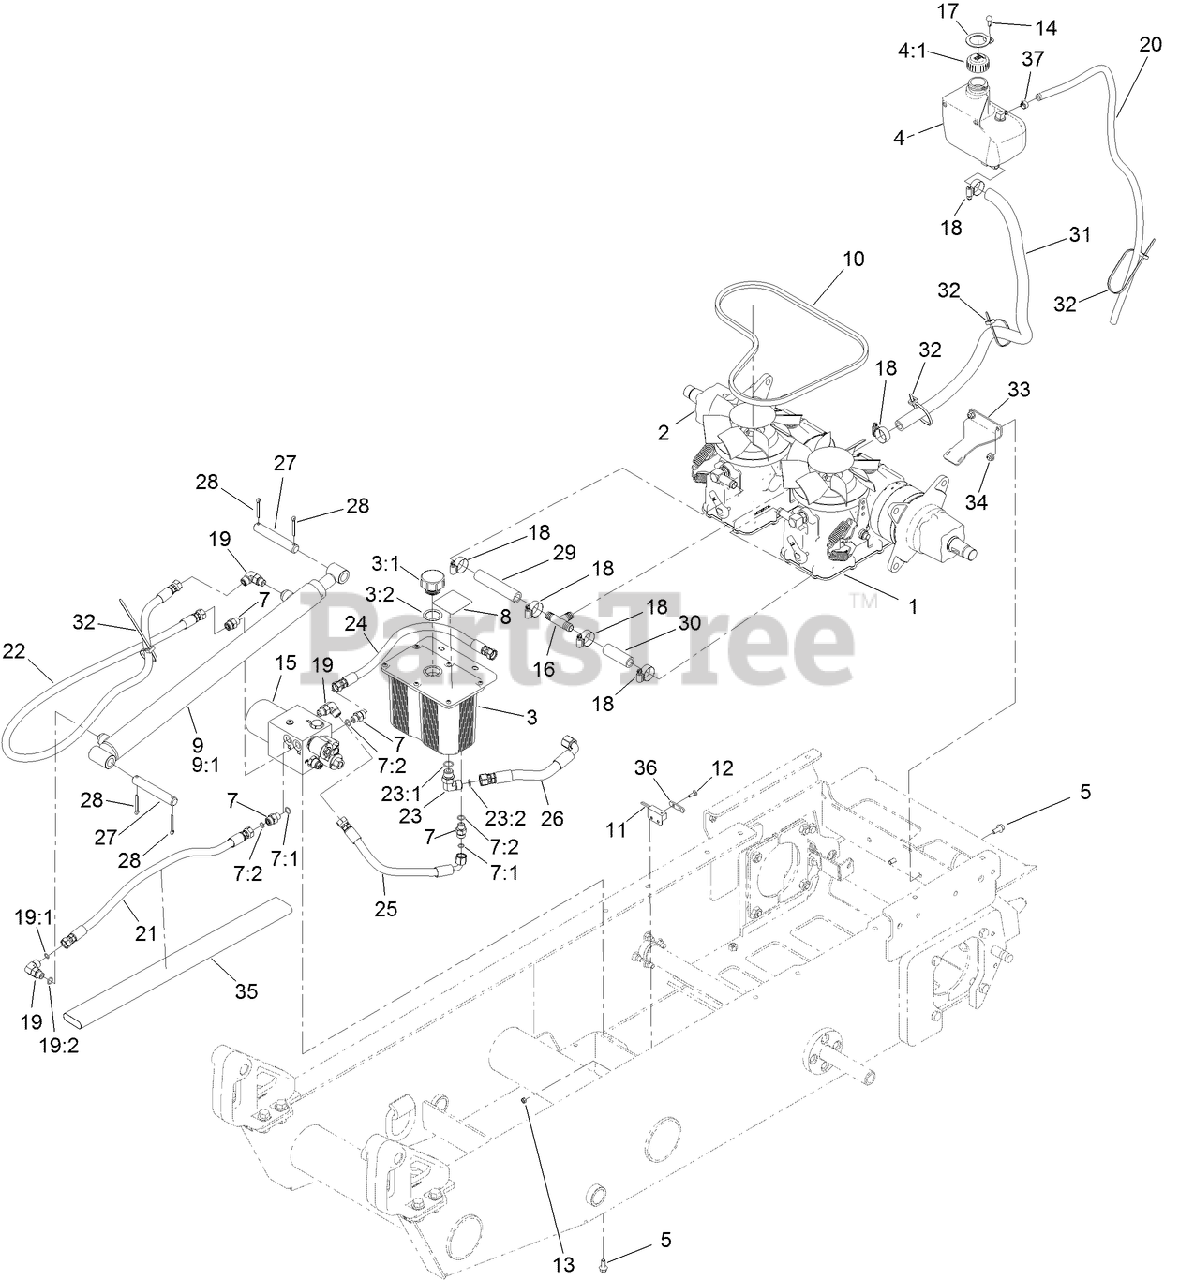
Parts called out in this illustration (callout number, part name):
1	LH HYDRO TRANSAXLE ASM
2	RH HYDRO TRANSAXLE ASM
3	TANK-HYDRAULIC
3:1	CAP-RESERVOIR, HYD
3:2	GASKET-CAP
4	TANK-HYD
4:1	CAP-VENTED
5	SCREW-HHF
7	FITTING-STRAIGHT
7:1	O-RING
7:2	O-RING
8	DECAL-WARNING
9	CYLINDER-HYDRAULIC
10	BELT
11	SWITCH-PROXIMITY
12	SCREW-CARR
13	NUT-LOCK, NI
14	SCREW-SELFDR
15	HYDRAULIC MANIFOLD ASM
17	LOCK-TANK
18	CLAMP-HOSE
19	FITTING-ELBOW, 90 DEG
19:1	O-RING
19:2	O-RING
20	HOSE-BREATHER, TRANSMISSION
21	HOSE-HYDRAULIC
22	HOSE-HYDRAULIC
23	FITTING-ELBOW-90 DEG
23:1	O-RING
23:2	O-RING
24	HOSE-HYDRAULIC
25	HOSE-HYDRAULIC
26	HOSE-HYDRAULIC
27	Pin-Pivot
28	PIN-COTTER
29	HOSE-HYD, HYDRO
30	HOSE-HYD, HYDRO
31	HOSE-HYD, HYDRO
32	TIE-CABLE
33	BRACKET-HOSE RETAINER
34	NUT-HF, NI
35	SLEEVE-PROTECTIVE
36	PLATE-SWITCH, PROXIMITY
37	CLAMP-HOSE
